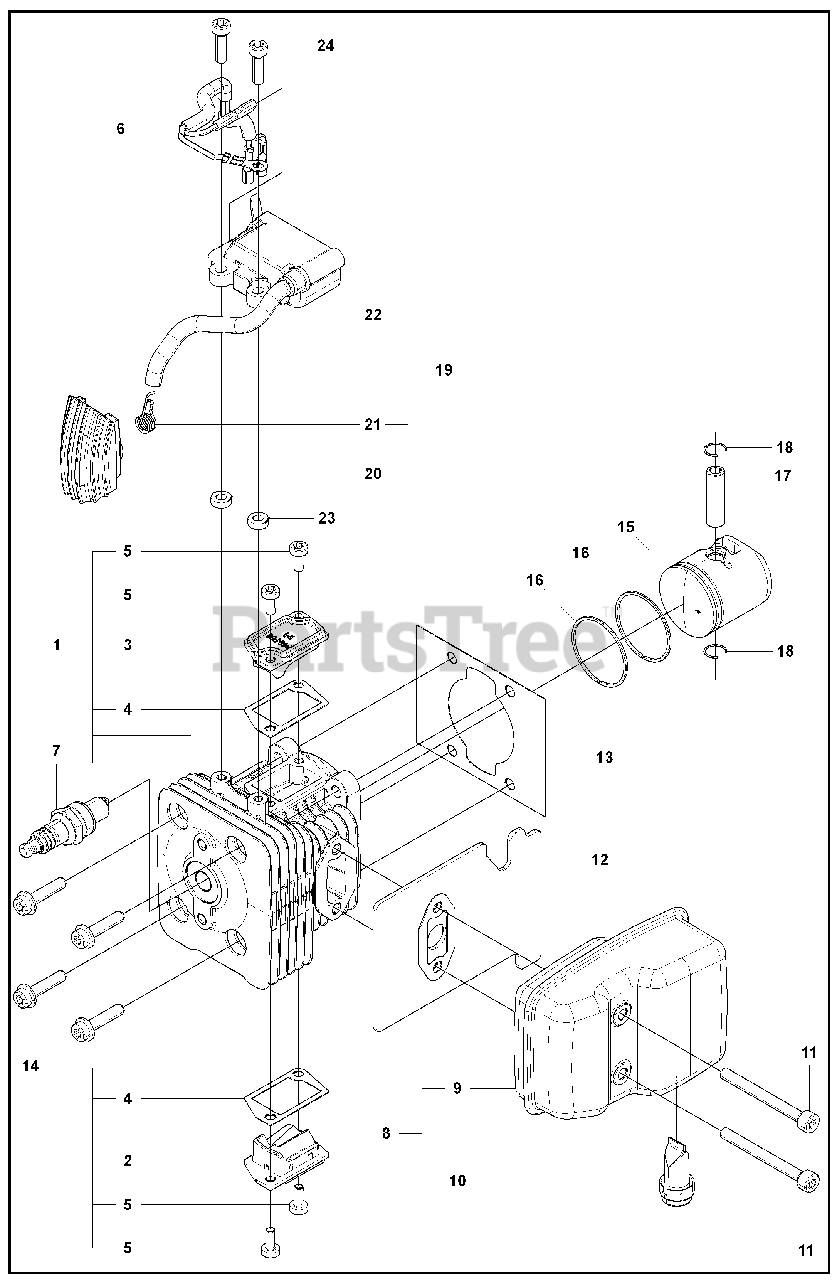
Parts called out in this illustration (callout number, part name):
1	CYLINDER COMP.
2	COVER, TR-S
3	COVER, TR-F
4	GASKET, TR
5	BOLT
6	CORD COMP.
7	SPARK PLUG NGK CMR7H
9	MUFFLER
11	BOLT TORX M5xL50 T27
12	GASKET, muff
13	GASKET, base
14	BOLT TORX
17	PIN
18	RING
19	COIL ASSY
20	CAP
23	SPACER
24	BOLT TORX M4xL16 T27
